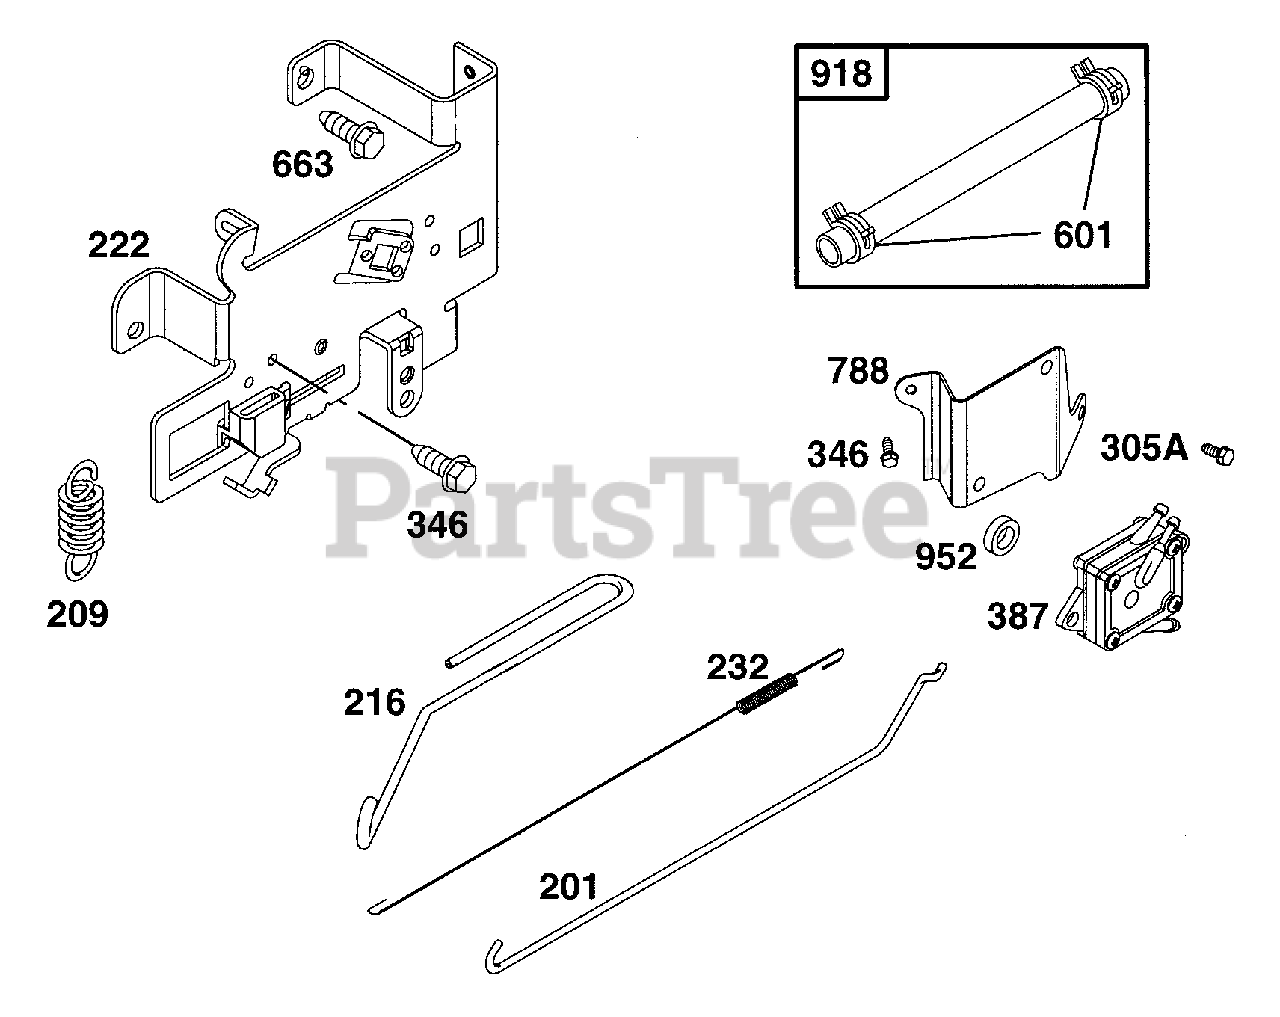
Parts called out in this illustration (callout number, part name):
201	Mech. Governor Link
209	Governor Spring
216	Choke Link
222	Control Bracket
232	Link Spring
305A	Hex Screw
346	Hex Screw
387	Fuel Pump
601	Hose Clamp
663	Hex Screw
788	Pump Bracket
918	Vacuum Hose
